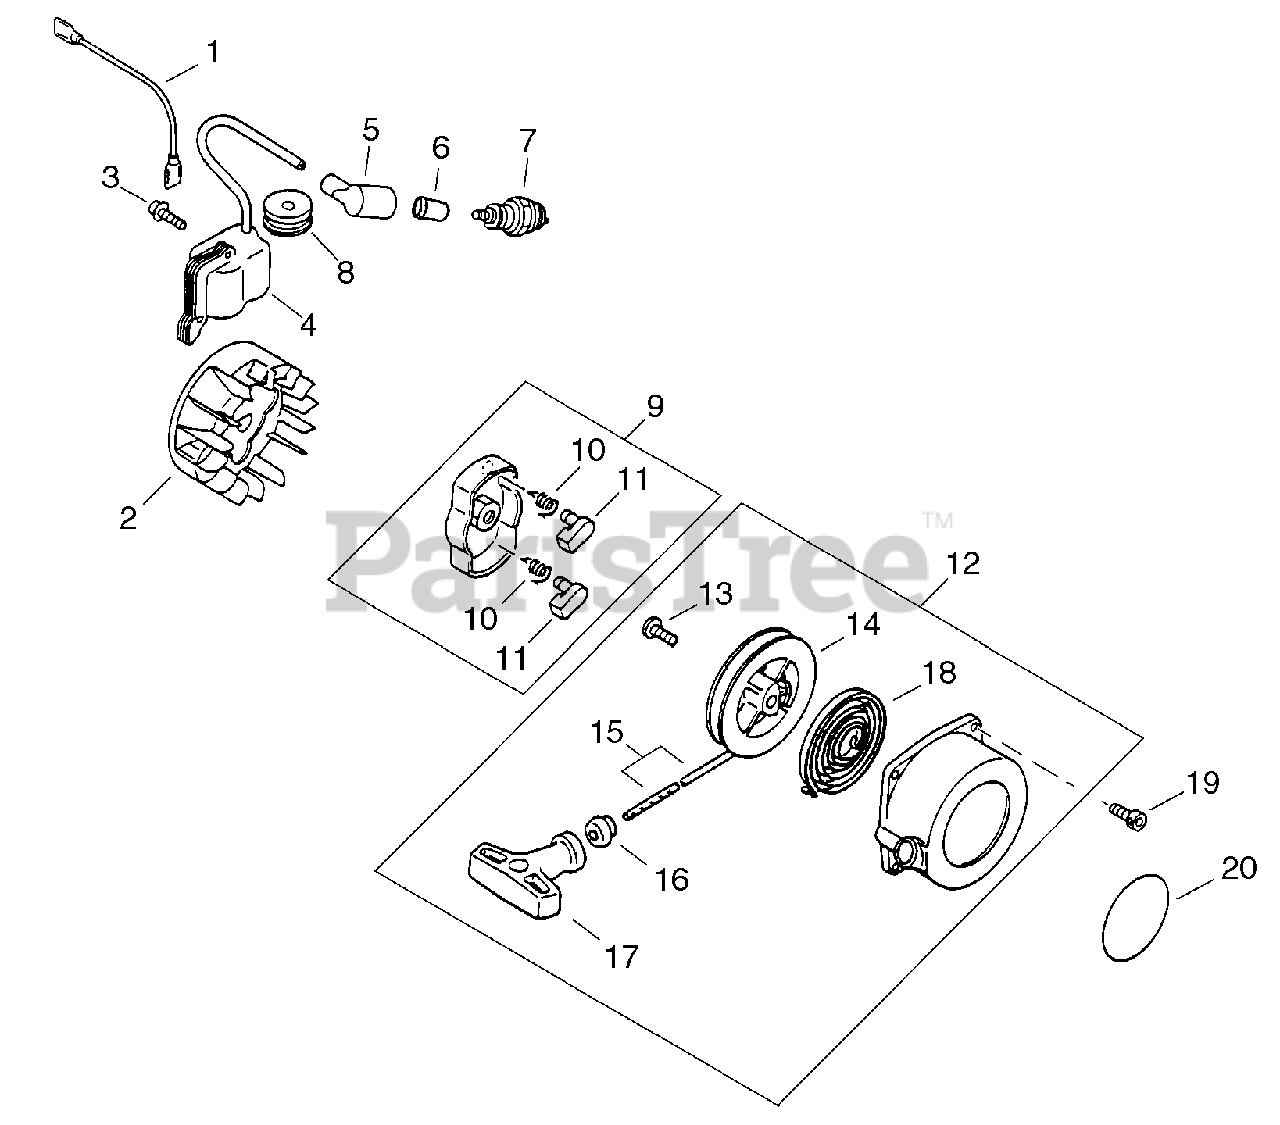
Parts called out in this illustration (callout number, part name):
1	LEAD - IGNITION
2	FLYWHEEL
3	SCREW - 4X22
4	COIL, IGNITION
5	CAP, SPARK PLUG
6	ADAPTER, SPARK PLUG CAP
7	SPARK PLUG -- BPMR-7A
8	GROMMET
9	STARTER PAWL ASSY
10	SPRING, RETURN
11	PAWL, STARTER - BLACK
12	STARTER ASSY
14	REEL, ROPE
15	ROPE, STARTER - 3X1000
16	GUIDE, ROPE
17	GRIP, STARTER
18	SPRING, REWIND
19	SCREW - 4X16
20	LABEL - ECHO
